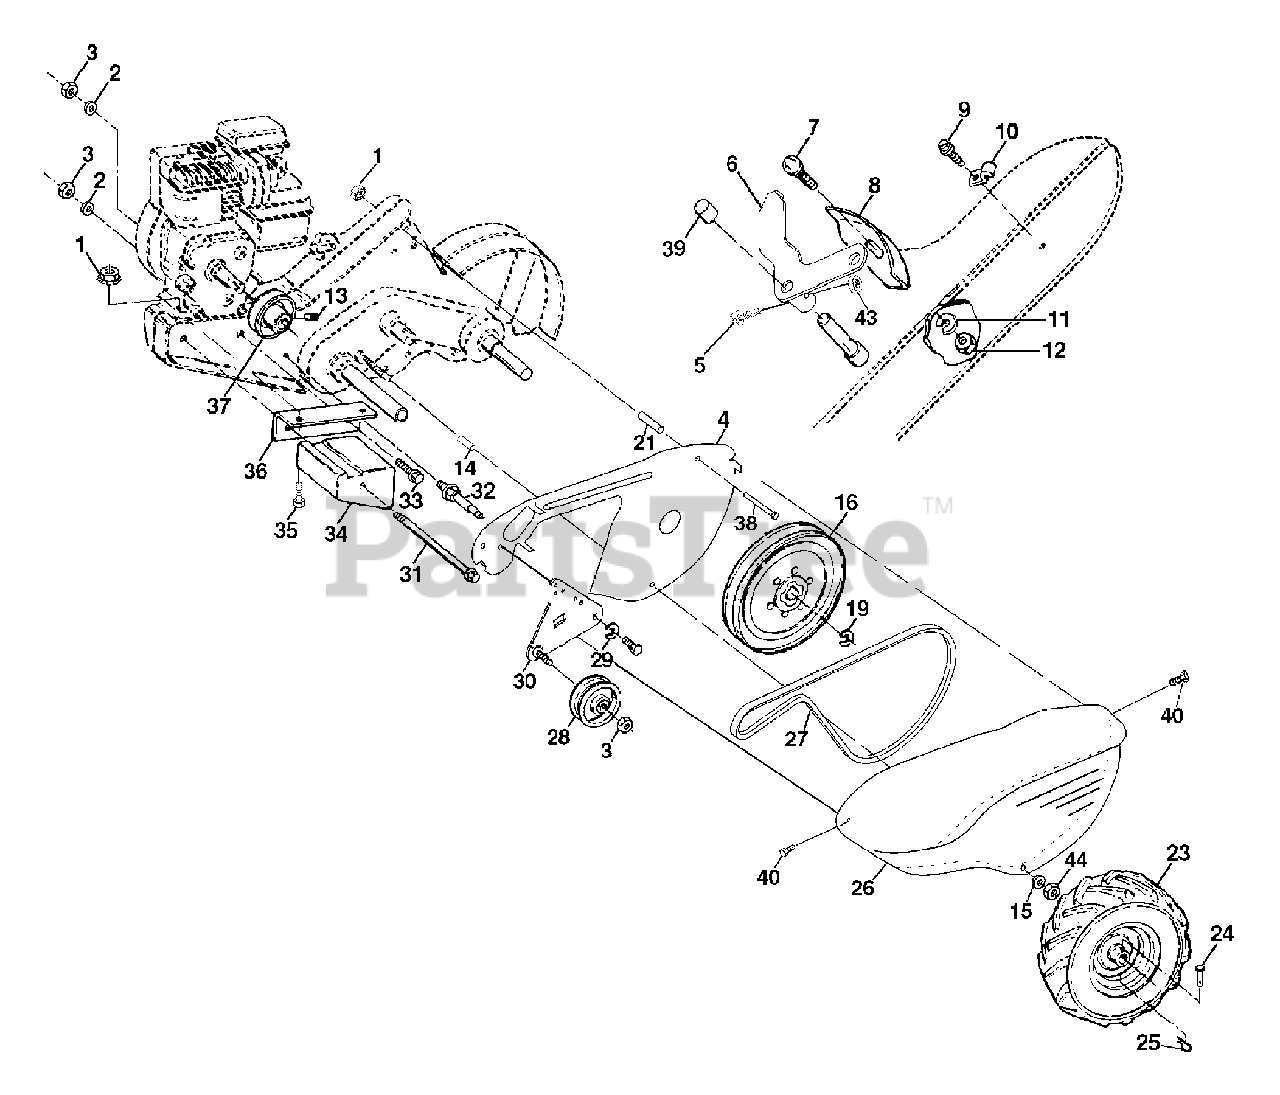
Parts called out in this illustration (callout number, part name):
1	Nut, Keps 5/16-18
2	Washer, Lock 3/8
3	Nut, Hex 3/8-16
4	Shield Inner Belt Guard
5	Screw Shift Lever
6	Lever, Shift
7	Bolt, Carriage 1/4-20 x 1/2 Gr. 5
8	Plate, Shift Indicator
9	Screw, Hex, Washer Head, Slotted #10-24 x 1/2
10	Clip
11	Washer, Lock 1/4
12	Nut, Hex 1/4-20
13	Screw, Set, Hex 5/16-18 x 3/8
14	Spacer, Split 0.327 x 0.42 x 1.220
15	Washer 11/32 x 11/16 x 16 Ga.
16	Sheave, Transmission
19	Ring, Retainer
21	Spacer, Split 0.327 x 0.42 x 2.09
22	Bolt Fin Hex 5/16-24 x 1/2
23	Tire
23	Rim
23	Tire Valve
24	Rivet, Drilled
25	Clip, Hairpin
26	Guard, Belt
27	Belt, V
28	Pulley, Idler
29	Ring, Klip
30	Bracket, Idler
31	Bolt, Hex 5/16-16 x 12
32	Shaft, Idler Arm
33	Bolt, Hex 3/8-16 x 1
34	Counterweight, L. H.
35	Bolt, Hex 5/16-18 x 1-1/2
36	Bracket, Reinforcement, L. H.
37	Sheave, Engine
38	Bolt Fin Hex 5/16-18 x 2-3/4
39	Cap, Plunger Blk
40	Screw Hex Wsh. SLT #10-24 x .50
43	Nut Lock #10-24
44	Nut Lock Hx W/Ins 5/16-18
